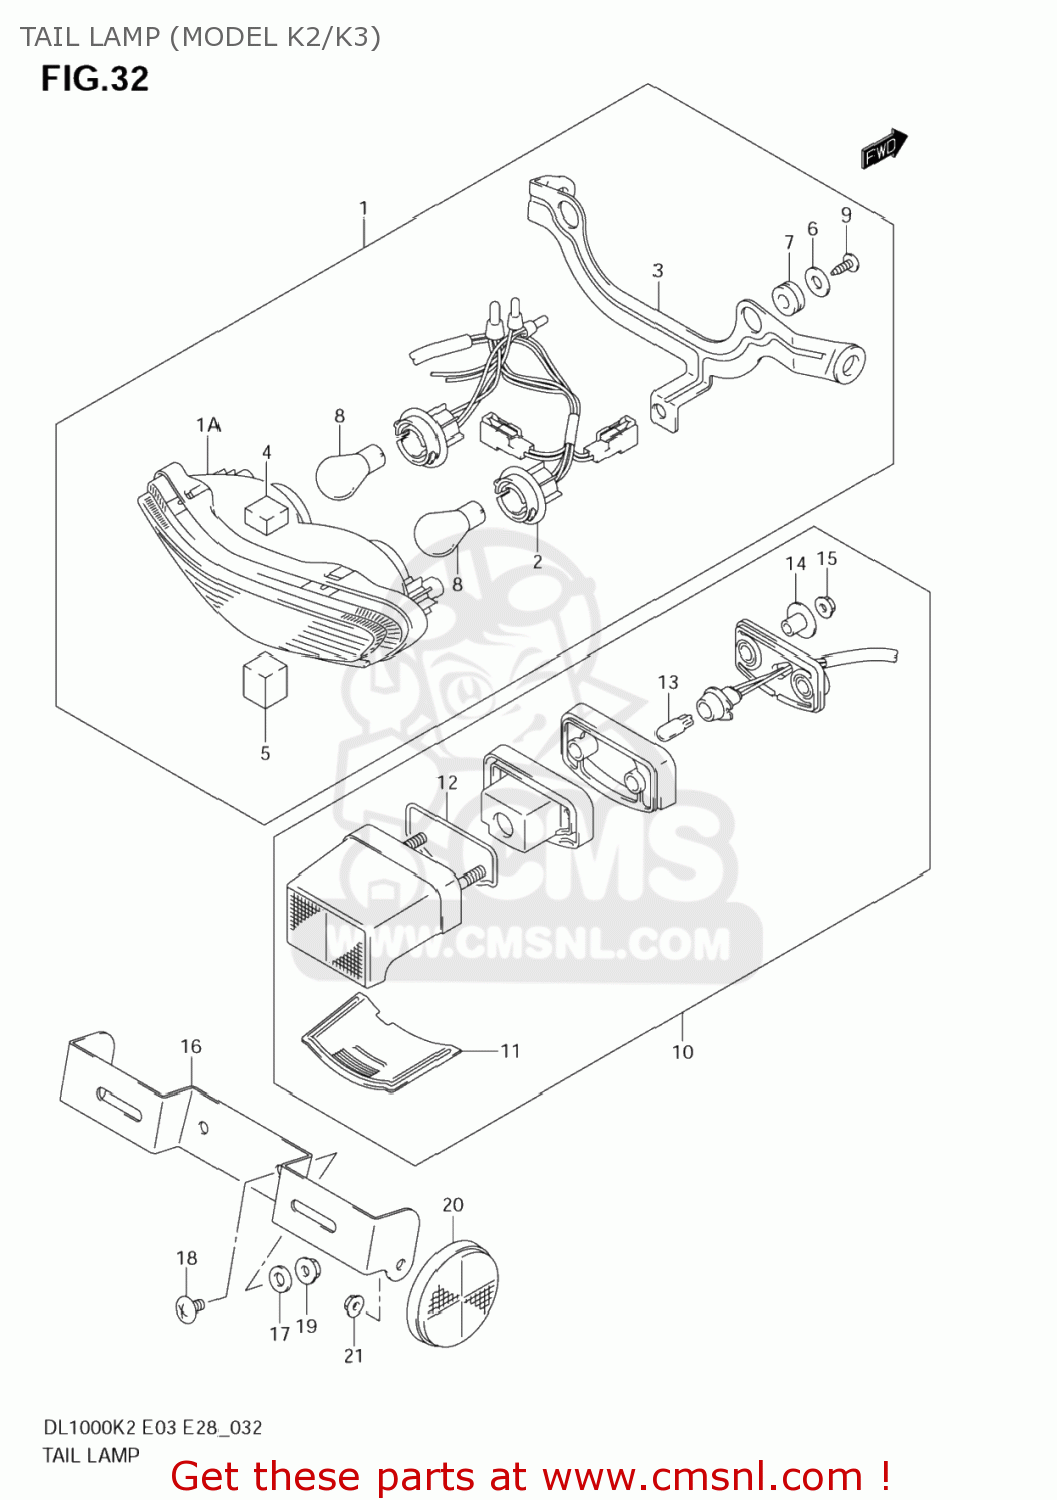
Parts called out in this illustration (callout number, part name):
1	LAMP ASSY,RR COMBINATION
1A	UNIT
2	SOCKET & CORD ASSY
3	BRACKET
4	CUSHION,UPR(20X20X12)
5	CUSHION,LWR(20X20X25)
6	WASHER(5.5X20X1.2)
7	CUSHION
8	BULB(12V21/5W)
9	SCREW
10	LAMP ASSY, LICENSE
11	LENS
12	GASKET (NAS)
13	BULB(12V5W)
14	SPACER
15	NUT
16	BRACKET,LICENSE PLATE
17	WASHER(6.5X15X1.6)
18	SCREW 6X12
19	NUT
20	REFLECTOR ASSY,RR SIDE
21	NUT
